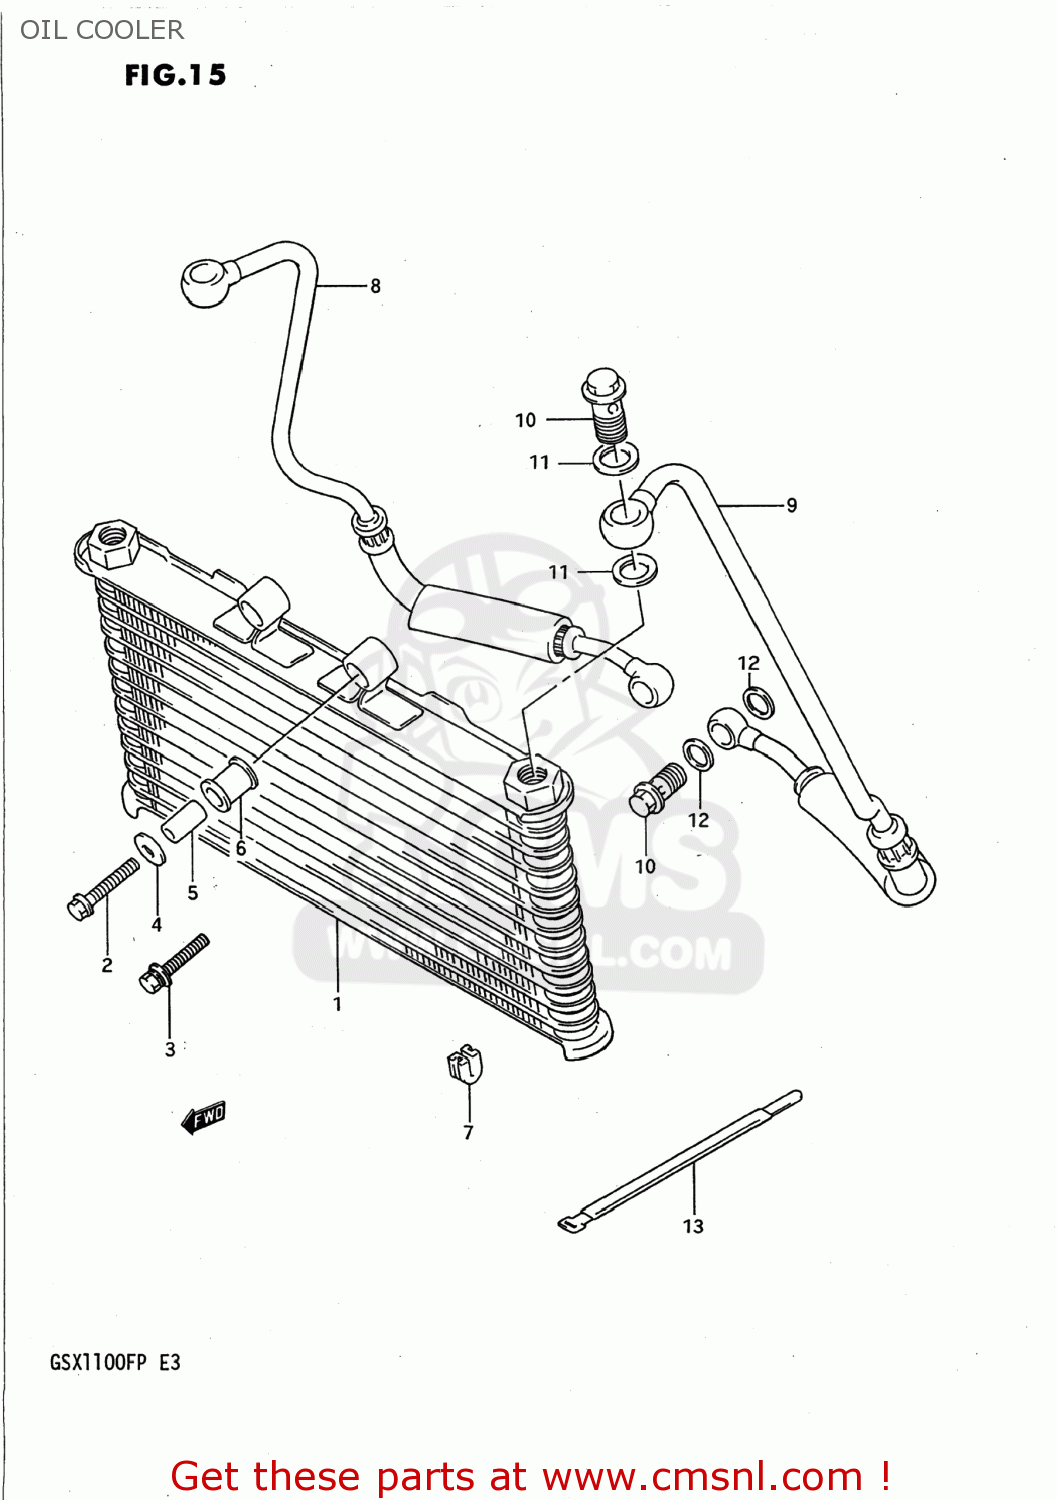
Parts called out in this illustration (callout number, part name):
1	COOLER ASSEMBLY,OIL
2	BOLT 8X40
3	BOLT(8X40)
4	WASHER(8.5X23X1.2)
5	SPACER (8.8X12X24.5)
6	CUSHION,OIL COOLER NO.1
7	CUSHION,OIL COOLER NO.2
8	HOSE,OIL
9	HOSE,OIL
10	BOLT UNION
11	GASKET(16X22X2) (NAS)
12	GASKET(16X22X2) (NAS)
13	CLAMP
